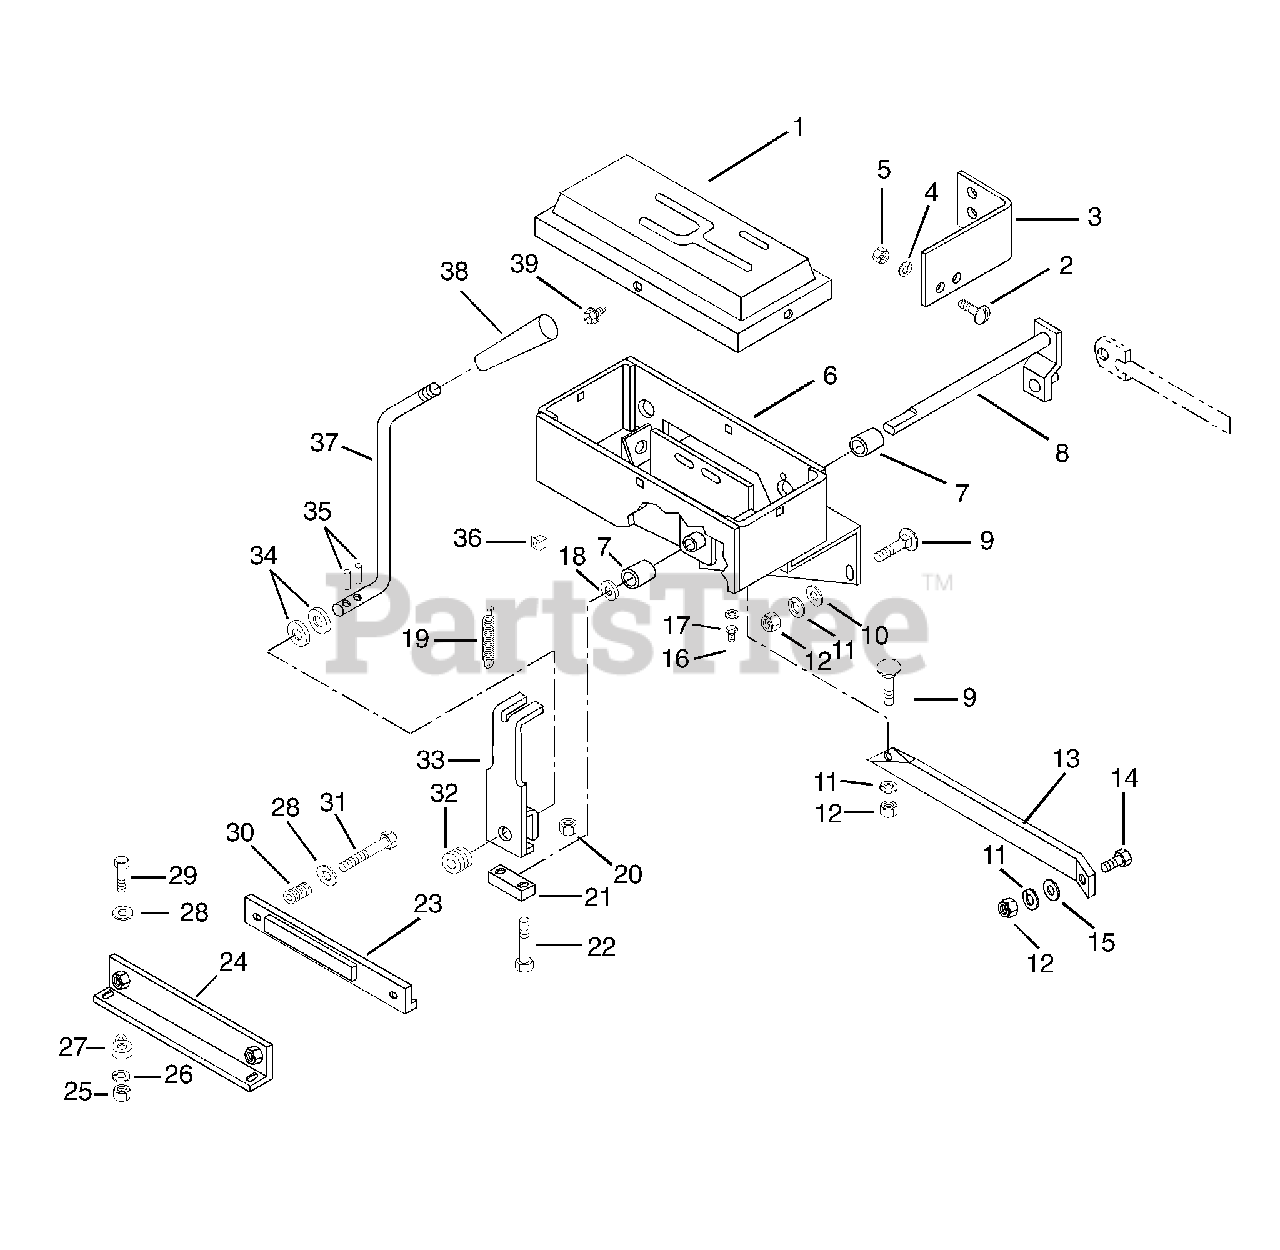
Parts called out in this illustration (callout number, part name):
1	CONTROL CONSOLE WITH COVER
2	@SCR-MCH 10-24X.50 HWH YWZC
3	BRACKET - SWITCH
4	@WSHR-LK #10X.047 REG YWZC
5	@NUT-HEX 10-24 YWZC
6	CONTROL BOX
7	BSHG-SLV .625X.750X1.000
8	SHIFT SHAFT
9	@BLT-RDHDSQNK .38-16X1.00 G2YZ
10	@WSHR-FL-STL.438X1.00X.083 YWZ
11	@WSHR-LK .38X.094 REG YWZC
12	@NUT-HEX .38-16 YWZC
14	@BLT-HEX .38-16X.75 GR5 YWZC
15	@WSHR-FL-STL.406X.812X.065 YWZ
16	FTG-LUBE .25-28X.256 YWZC
17	WSHR-LK .250X.047 LT YWZC
18	WSHR-FL-STL .630X1.005X.062 YZ
19	SG-TENS .072X.565X1.87
20	@NUT-LK-CTR .31-18 YWZC
22	@BLT-HEX .31-18X1.50 GR5 YWZC
23	L. H. FRICTION BRAKE
24	R.H. FRICTION BRAKE
25	@NUT-HEX .31-18 YWZC
26	WSHR-LK .312X.097 HVY YWZC
27	SPACER .344X.750X.625X.500
28	@WSHR-FL-STL.38X.875X.083 YWZC
29	@BLT-HEX .31-18X1.25 GR5 YWZC
30	SG-COMP .093X.59X1.50
31	SCR-MCH .31-18X2.75 SLRH YWZC
32	GROMMET .438ID X .688 OD
34	WSHR-FL-STL .52X.827X.062 YWZC
35	PIN-ROLL .188X.88
36	PLASTIC GROMMET
37	SHIFT ROD
39	SCR-TAP 10-12X.50 CRPH PL A BL
